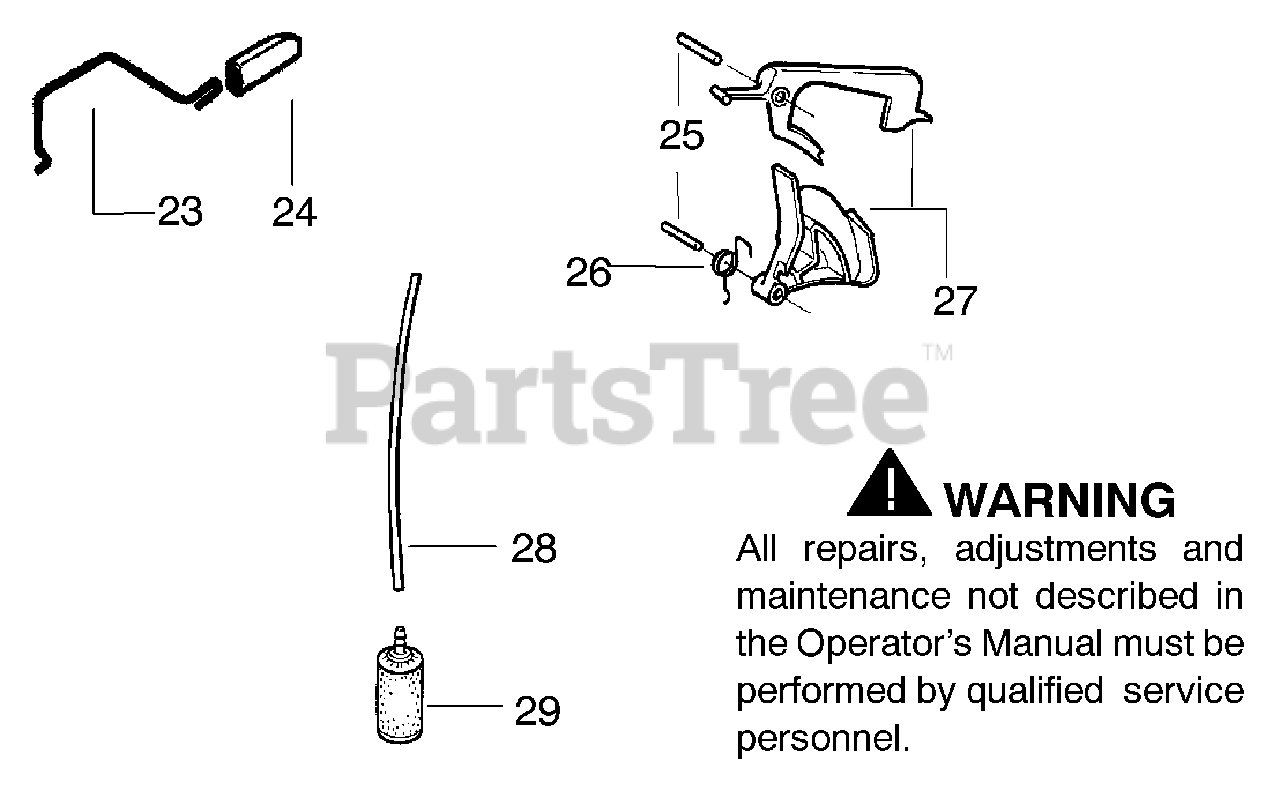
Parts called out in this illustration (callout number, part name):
23	Wire - Throttle
24	Cap - Wire
27	Kit - Throttle Trigger
28	Kit - Fuel line
29	Assy.- Fuel Pickup
